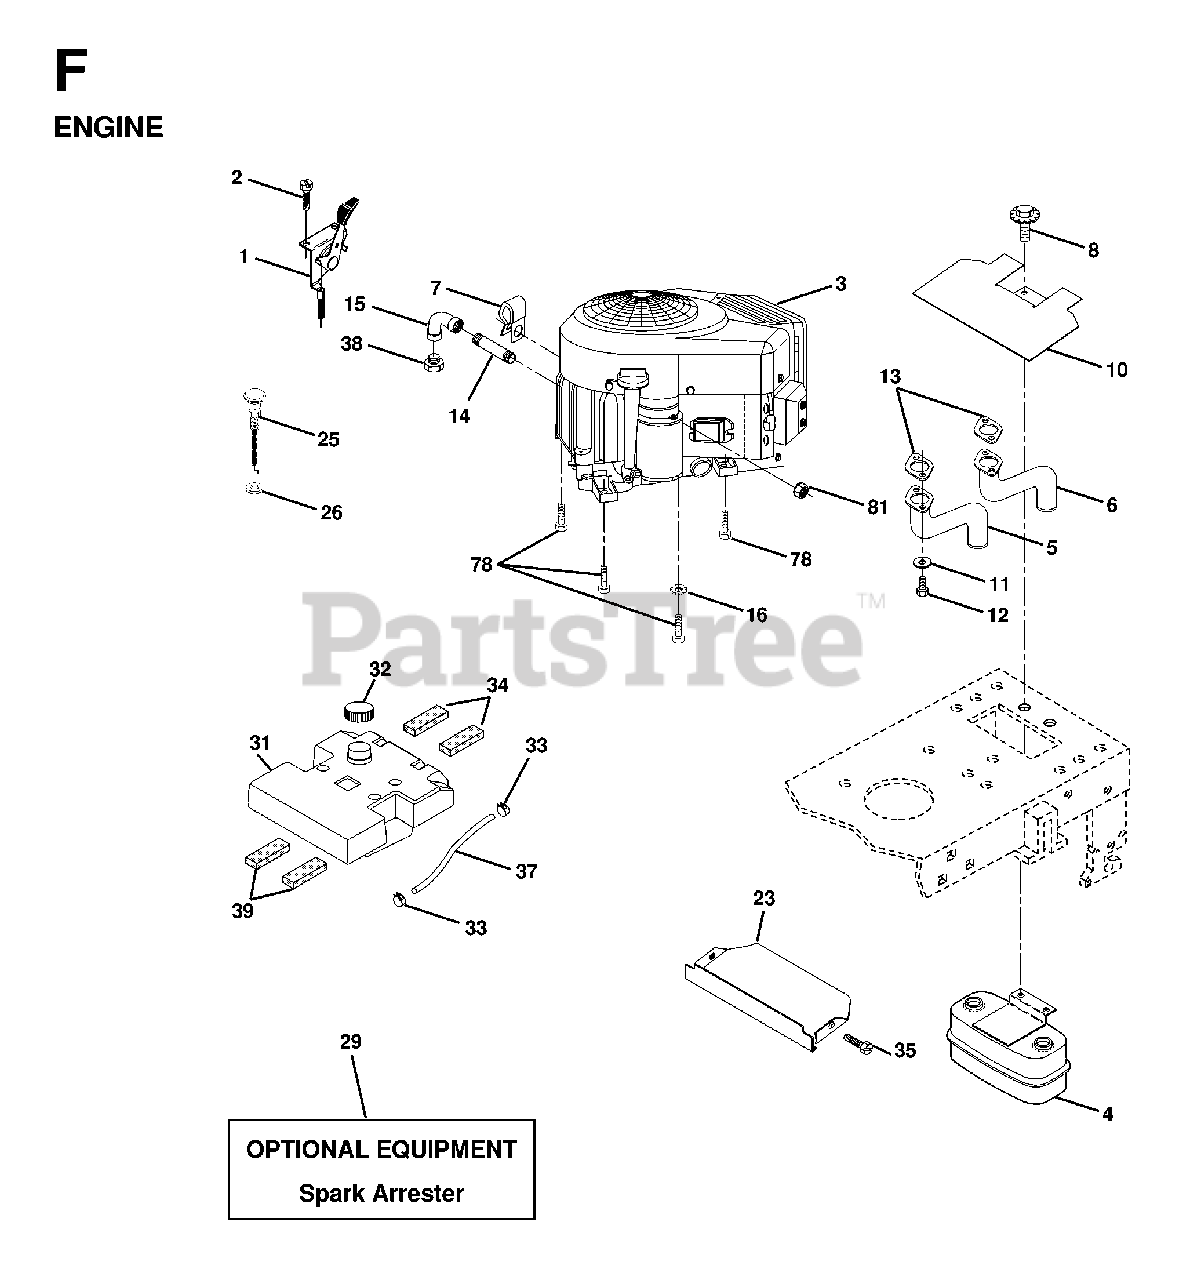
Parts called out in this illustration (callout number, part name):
1	CONTROL THROTTLE 36"
2	SCREW LT
4	MUFFLER.TWIN.CYL.LOW.TONE
5	TUBE ASSY EXH LH
6	TUBE ASSY EXH RH
8	BOLT HEX WASHER HD 5/16-18
10	SHIELD HEAT LT
14	PIPE NIPPLE LT
15	ELBOW
16	LOCKWASHER
23	PROTECTOR
25	CONTROL, CHOKE
26	NUT KEPS 3/8 - 24 UNF
29	ARRESTER SPARK (OPTIONAL)
31	TANK.FUEL(3.5.GAL)
32	FUEL CAP
33	HOSE CLAMP
34	PAD-SPACER LT
35	SCREW
39	PAD IDLER TI
40	BUSHING OUTLET T
78	SCREW
81	NUT FLANGE 1/4-20 STARTER NUT
